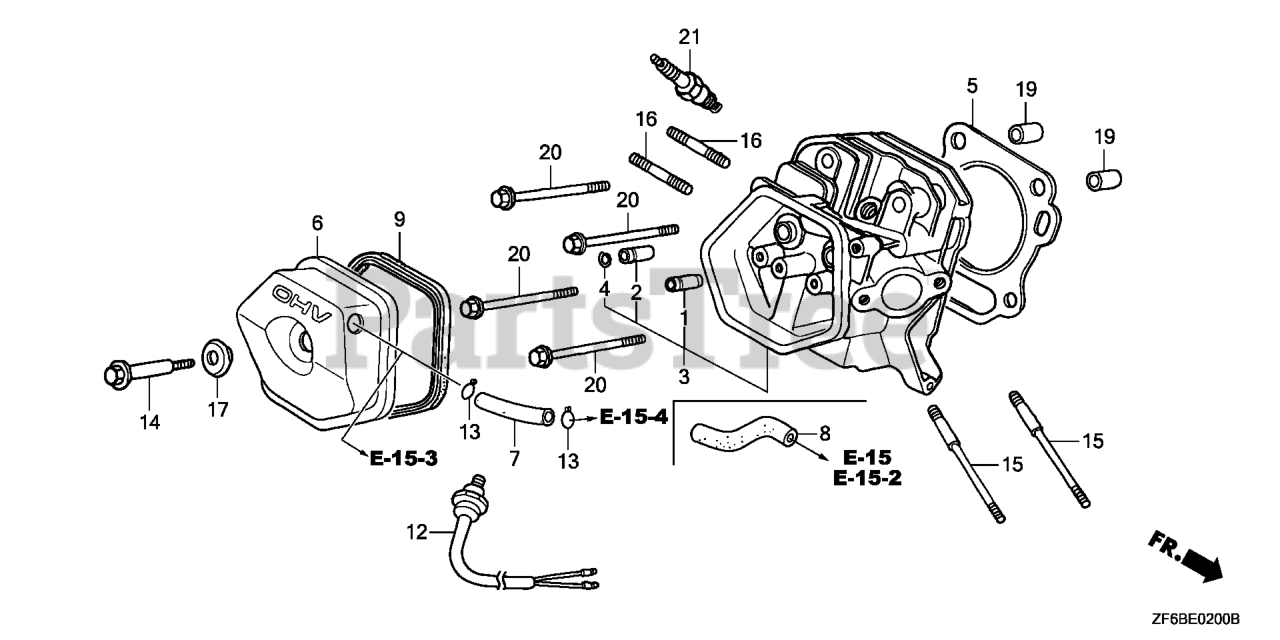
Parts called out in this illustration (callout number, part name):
3	CYLINDER HEAD
4	CLIP, VALVE GUIDE
5	GASKET, CYLINDER HEAD (NIPPON LEAKLESS)
6	COVER, HEAD
8	TUBE, BREATHER
9	GASKET, CYLINDER HEAD COVER
14	BOLT, HEAD COVER
15	BOLT, STUD (8X131.5)
16	BOLT 2, STUD (8X32)
17	WASHER, HEAD COVER
19	PIN A, DOWEL (12X20)
20	BOLT, FLANGE (10X80)
21	SPARK PLUG (BPR5ES) (NGK)
21	SPARK PLUG (W16EPR-U) (DENSO)
21	SPARK PLUG (BPR6ES) (NGK)
